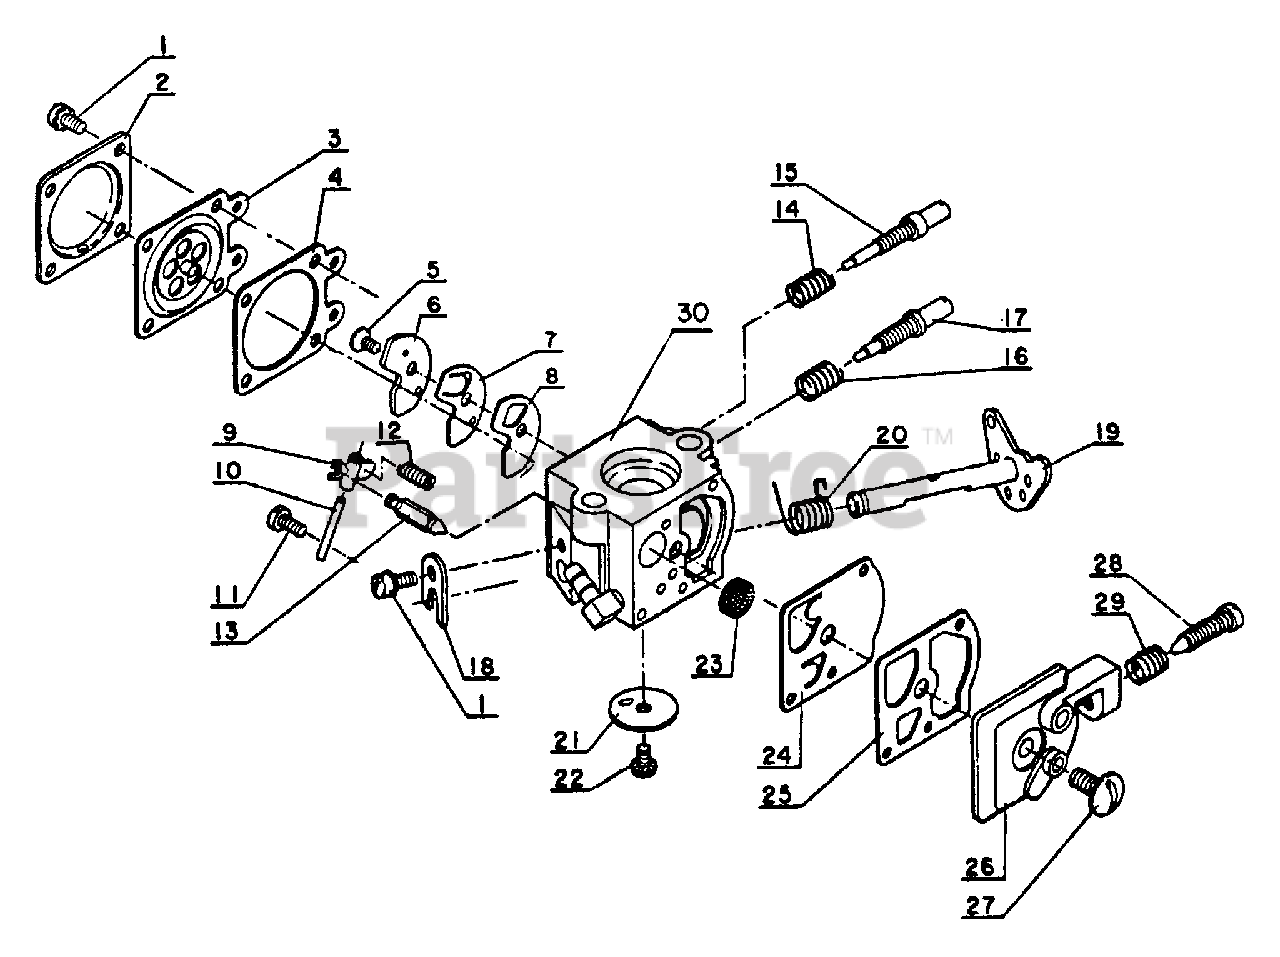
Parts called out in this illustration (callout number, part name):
2	COVER, METERING DIAPHRAGM
3	DIAPHRAGM, METERING
4	GASKET, METERING DIAPHRAGM
5	SCREW, CIRCUIT PLATE
6	PLATE, CIRCUIT
7	VALVE, CHECK
8	GASKET, CIRCUIT PLATE
9	LEVER, METERING
10	PIN, METERING LEVER
11	SCREW, METERING LEVER PIN
13	VALVE, INLET NEEDLE
14	SPRING, NEEDLE
15	NEEDLE, HIGH SPEED
16	SPRING, NEEDLE
17	NEEDLE, IDLE
18	CLIP, THROTTLE SHAFT
19	SHAFT, THROTTLE
20	SPRING, THROTTLE RETURN
21	VALVE, THROTTLE
23	STRAINER
24	DIAPHRAGM, FUEL PUMP
25	GASKET, FUEL PUMP
26	COVER, PUMP
28	SCREW, IDLE ADJUST
29	SPRING, IDLE ADJUST
30	BODY, CARBURETOR
